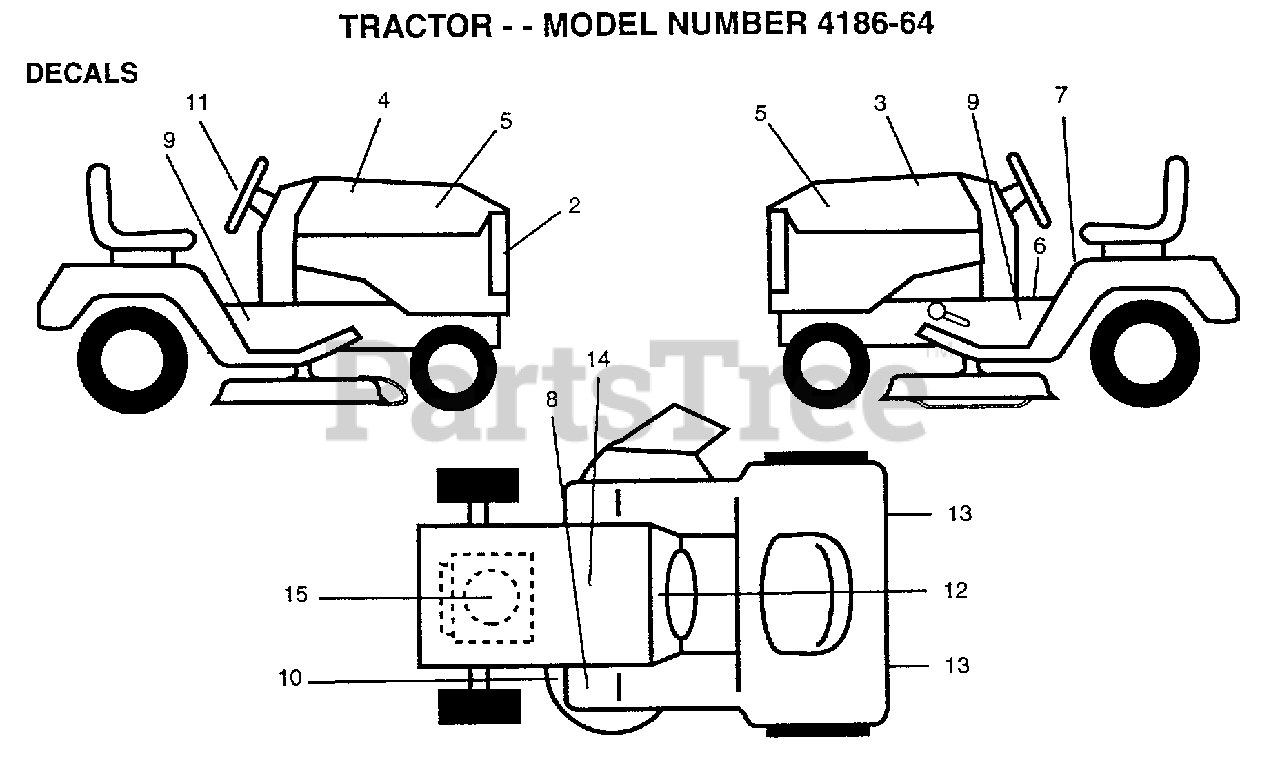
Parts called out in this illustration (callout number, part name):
2	GRILL DECAL
3	HOOD DECAL LH
5	NAMEPLATE LOGO
6	DECAL BRAK PARK
7	DECAL
9	DECAL.CHASSIS.18H
10	"DECAL.V.BELT.44"""
12	DECAL.DASH.INST.
13	REFLECTOR-TAIL YT
14	DECAL.BTRY.DANGER
15	DECAL ENGINE
